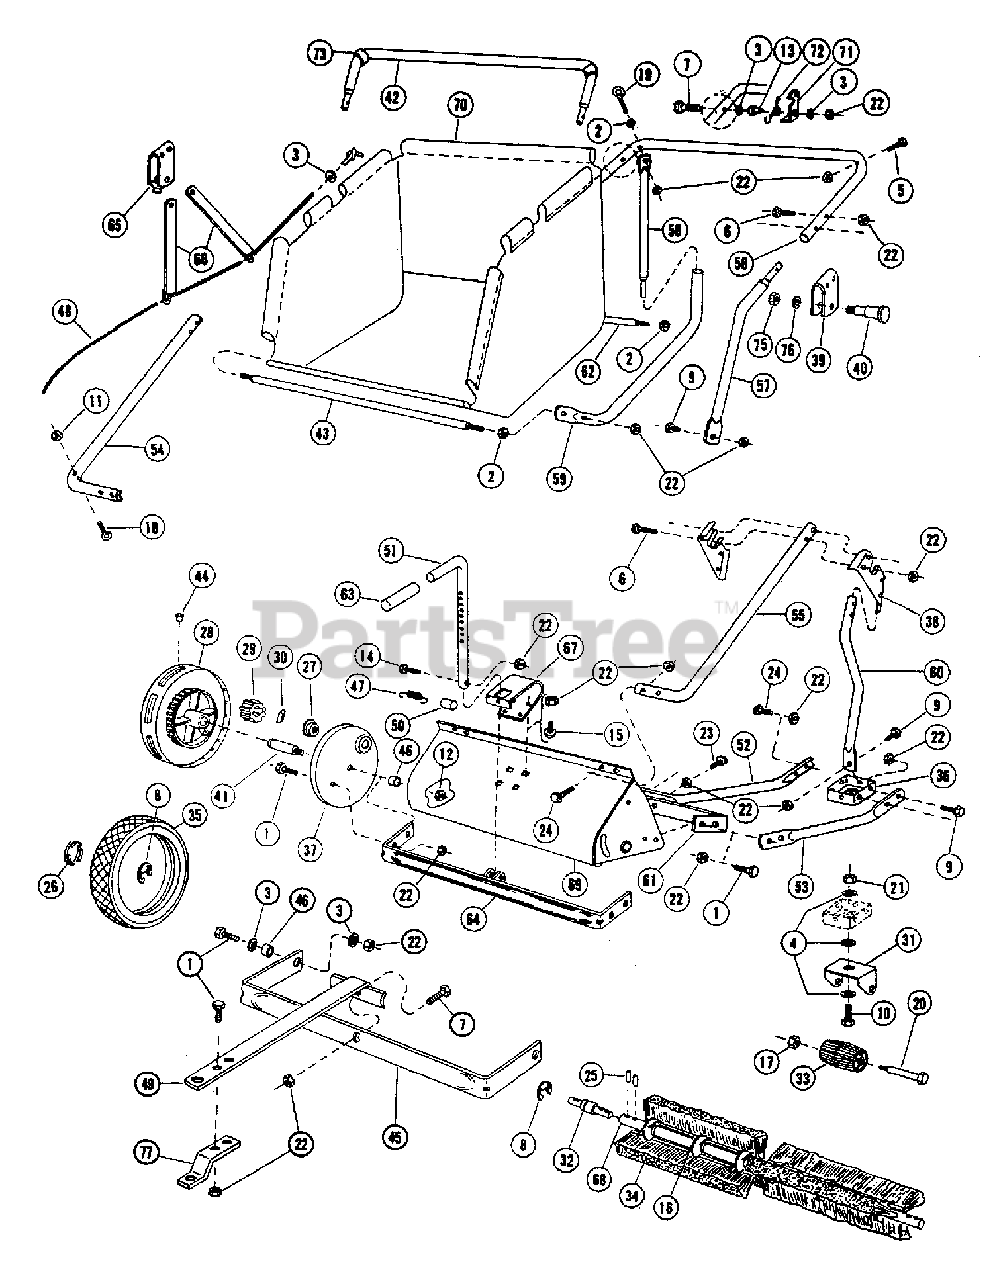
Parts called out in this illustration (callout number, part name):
1	CAPSCREW, 5/16-18 x 3/4
2	NUT, 5/16-18
3	WASHER, 5/16 SAE, Flat
4	WASHER, 1/2, SAE, Flat
5	CAPSCREW, Hexagon, 5/16-18 x 1
6	CAPSCREW, Hexagon, 5/16-18 x 1-1/4
7	CAPSCREW, Hexagon, 5/16-18 x 1-1/2
8	RING, Retaining, 5/8, E-Type
9	CAPSCREW, Hexagon, 5/16-18 x 1/2
10	CAPSCREW, Hexagon, 1/2-13 x 1-1/4
11	NUT, Lock, 1/4-20
12	NUT, Lock, 3/8-24
13	NUT, Pilot, 5/16-18
14	CAPSCREW, Hexagon, 5/16-18 x 1-3/4
15	BOLT, Carriage, 5/16-18 x 3/4
16	STRING, Brush Holder
17	NUT, Lock, 3/8-24
18	EYEBOLT, 1/4-20
19	EYEBOLT, 5/16-18
20	STUD, Caster
21	NUT, Lock, 1/2-13
22	NUT, Lock, 5/16-18
23	BOLT, Tube, 5/16-18 x 1-1/4
24	BOLT, Tube, 5/16-18 x 1
25	PIN, Roll, 3/16 Diameter x 7/8
25	CAPSCREW, Hexagon, 1/4-20 x 1
27	BEARING, Flanged
28	WHEEL ASSEMBLY, Die Cast
29	GEAR, Pinion
30	PAWL, Pinion
31	BRACKET, Caster
32	AXLE, Brush Stud
33	ROLLER, Caster
34	STRIP, Brush
35	TIRE, 10" x 2.25
36	PLATE ASSEMBLY, Caster
37	SHIELD, Wheel
38	BREACKET, Frame Pivot
39	BREACKET, Hamper Pivot
40	PIN, Pivot
41	ANCLE, Wheel Stuf
42	TUBE, Pivot Stand
43	ROD, Tie, Front
45	BAR, Hitch "U"
47	SPRING, Adjustment
48	ROPE, Dump
50	TUBE, Spring Retaining
51	TUBE, Adjustment
52	BRACE, Pivot Stand
53	TUBE, Pivot Stand Bottom
54	TUBE, R.H. Pivot Support
55	TUBE, L.H. Pivot Support
56	TUBE, Top Hamper
57	TUBE, Side hamper
58	TUBE, Hamper Support
59	TUBE, Hamper Bottom
60	TUBE, L.H., Pivot Support
61	BAR, Stiffener
62	ROD, Rear Hamper
63	GRIP, Hand
64	BUMPER ASSEMBLY
65	BRACKET ASSEMBLY, Pivot
66	LEVER, Dump
67	BRACKET, Adjustment
68	AXLE ASSEMBLY
69	SHIELD ASSEMBLY
70	HAMPER ASSEMBLY
71	LATCH, Hamper
72	SPRING, Latch
73	SLEEVE, Rubber
75	NUT, Hexagon, 3/8-24
76	LOCKWASHER, Split, 3/8
77	BRACKET, Hitch Pin
